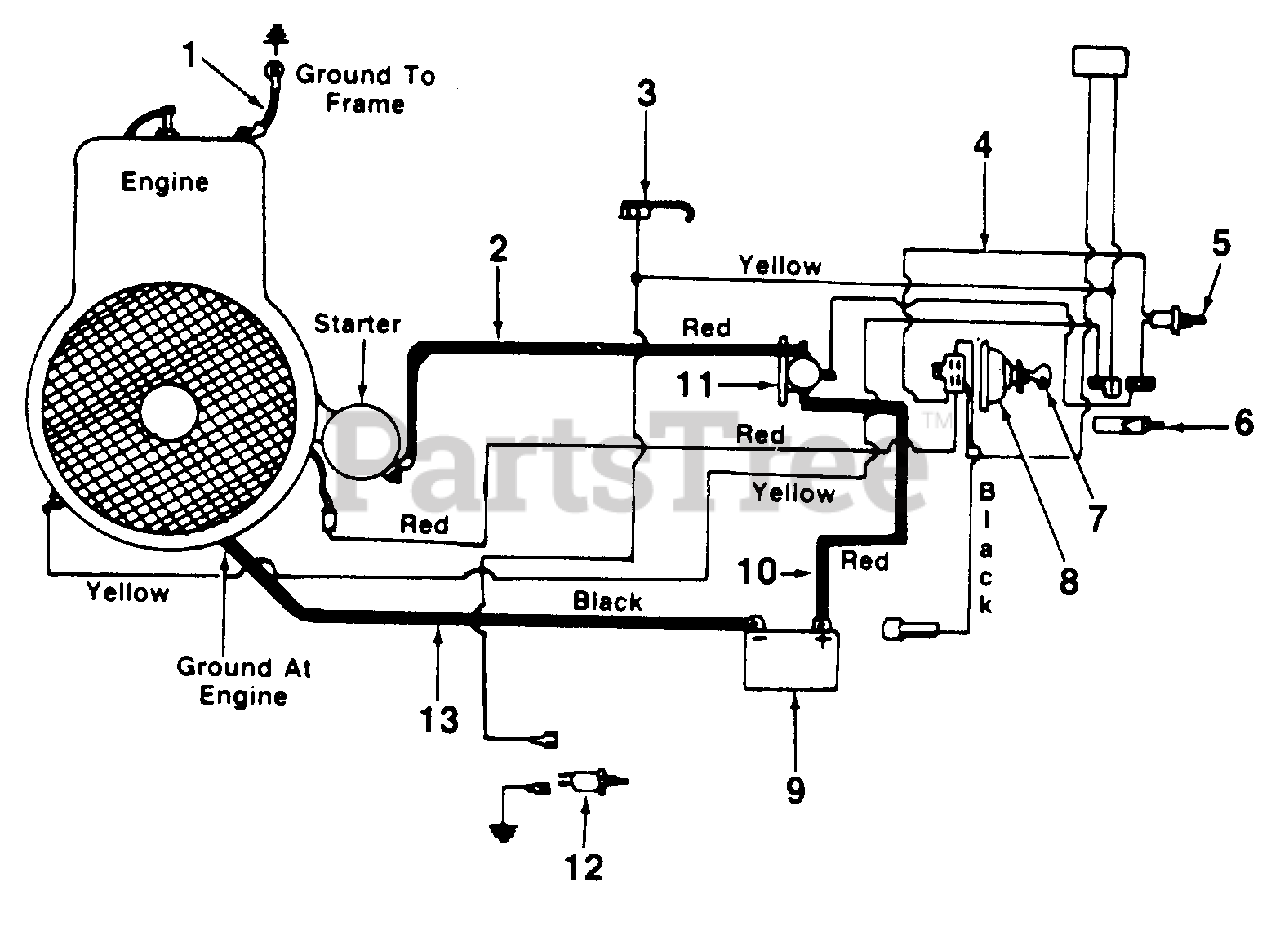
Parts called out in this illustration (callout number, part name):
1	Elec. Wire 8 Ga. x 9.0" Lg.
2	Elec. Wire
3	Spring Switch-Reverse
4	Wire Harness
5	Safety Switch-Black N.O.
6	Safety Switch
7	Ignition Key
8	Ignition Switch
9	Battery 12V
10	Elec. Wire Red w/Boot
11	Solenoid
12	Safety Switch Red N.C.
13	Elec. Wire 8 Ga. x 9.0" Lg.
